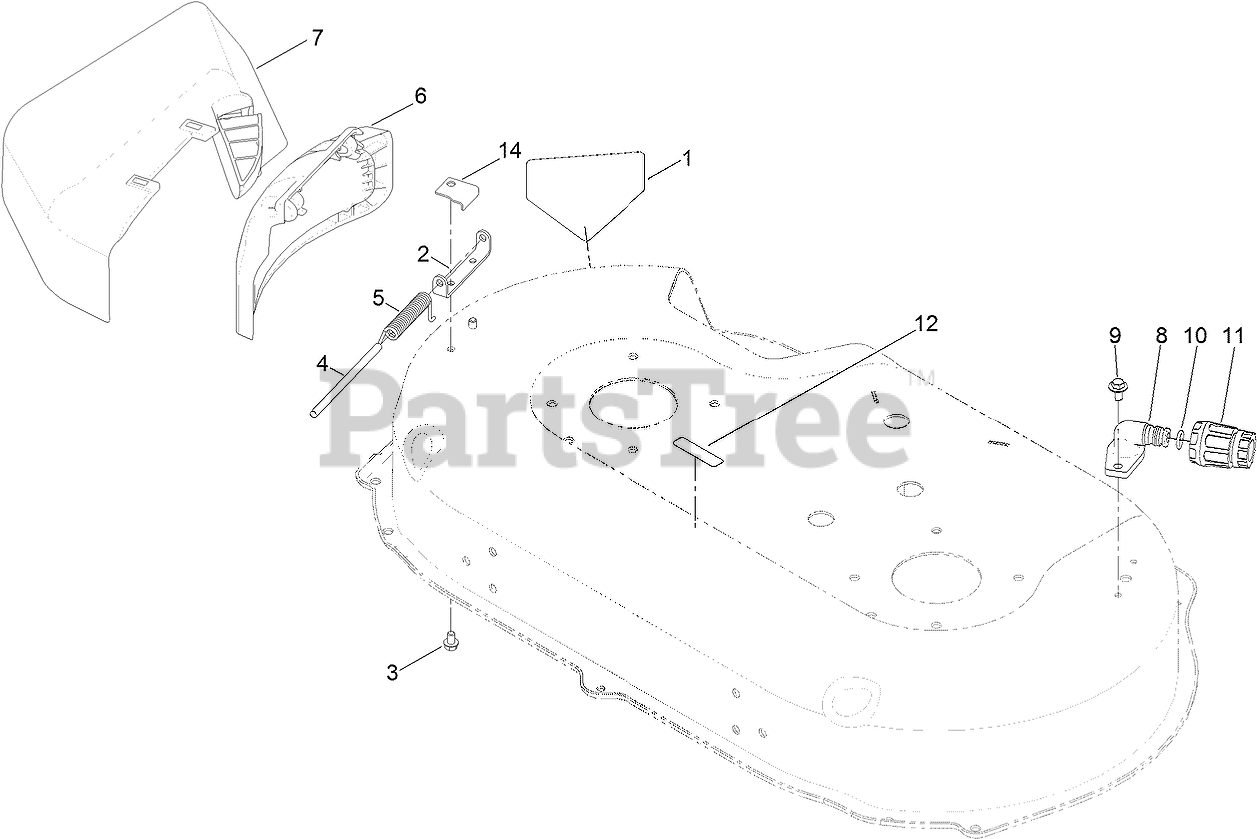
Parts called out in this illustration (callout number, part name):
1	DECAL-DANGER
2	BRACKET-COVER
3	SCREW-HWH
4	ROD-COVER
5	SPRING-TORSION, COVER
6	DEFLECTOR-SIDE
7	SIDE DISCHARGE CHUTE ASM
8	FITTING-WASHOUT
9	SCREW-HHFTF
10	O-RING
11	CONNECTOR-HOSE
12	DECAL-WARNING
14	PLATE-SPRING
